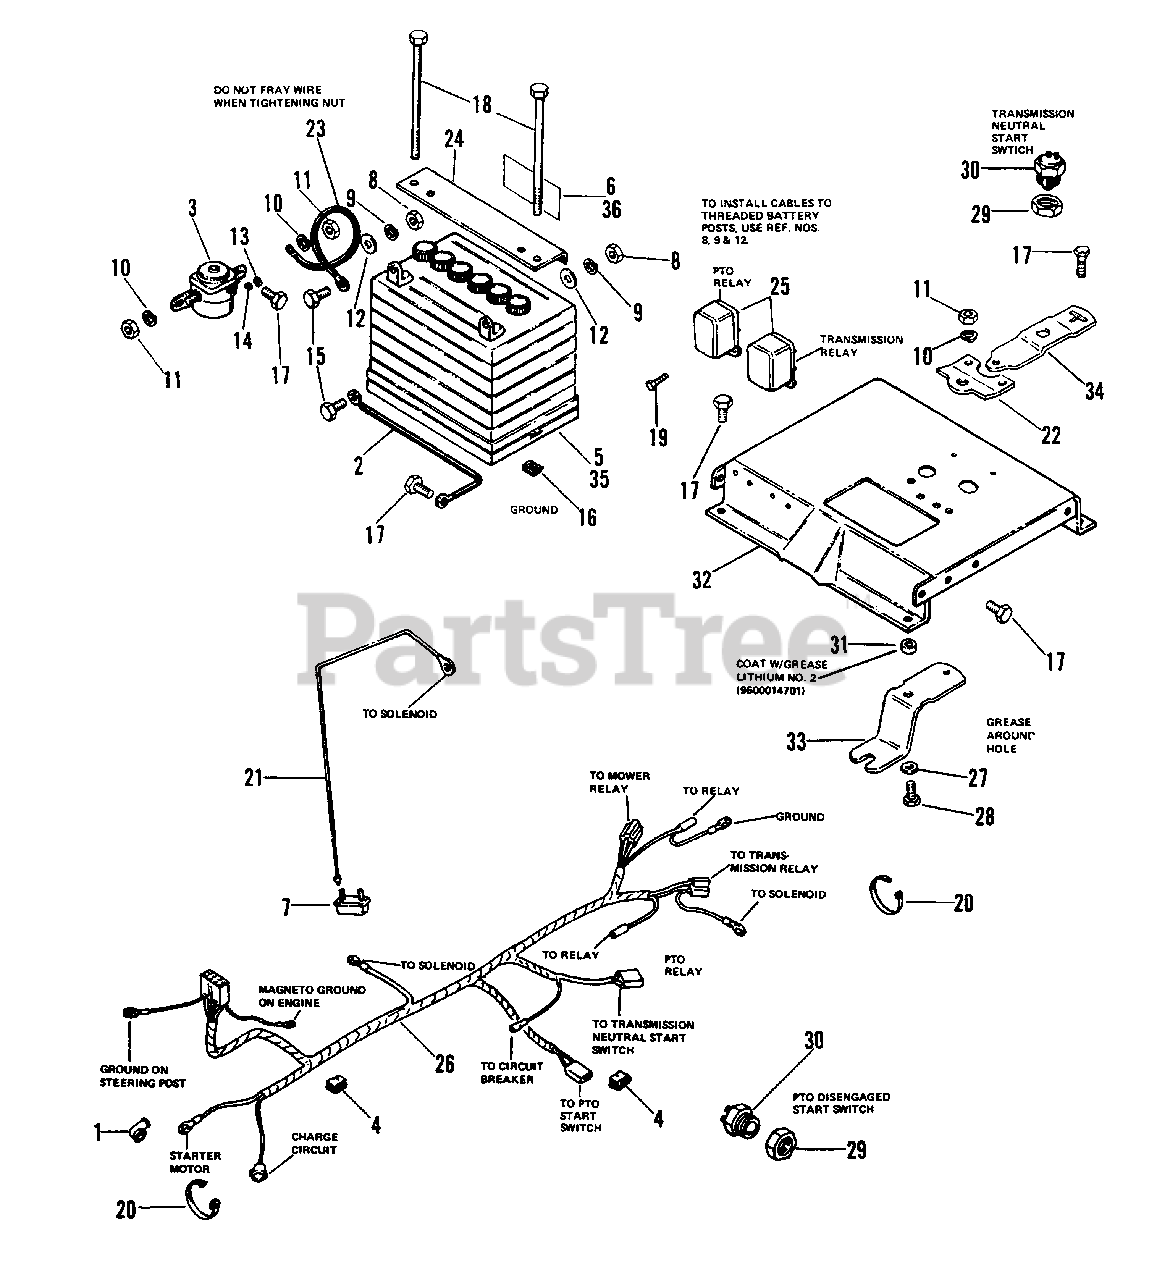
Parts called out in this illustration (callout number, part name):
1	COVER, Terminal
4	CLIP, Speed
7	BREAKER, Circuit
8	NUT, Hex, 1/4-20
9	LOCKWASHER, Spring, 1/4
10	LOCKWASHER, Spring, 5/16
11	NUT, Hex, 5/16-18
12	WASHER, Plain, 1/4
13	NUT, Hex Mach., No. 10
14	LOCKWASHER, Ext. No. 10
15	CAPSCREW, Hex Hd., 1/4-20 x 3/4 (6008)
16	NUT, Retainer, 1/4-20
17	SCREW, Hex Washer Hd, 1/4-20 x 3/8
18	CAPSCREW, Hex Hd., 1/4-20 x 7
19	SCREW, Hex Hd., No. 14 x 3/4
22	PIVOT, Shift Lever
24	HOLD DOWN, Battery
25	RELAY, 12 Volt
26	HARNESS, Lower
28	CAPSCREW, Hex Hd., 5/16-18 x 1
29	LOCKNUT, 9/16-18
30	SWITCH, Interlock
32	SUPPORT, Frame
33	LEVER, Switch
34	BRACKET, Switch
35	BATTERY (6010)
